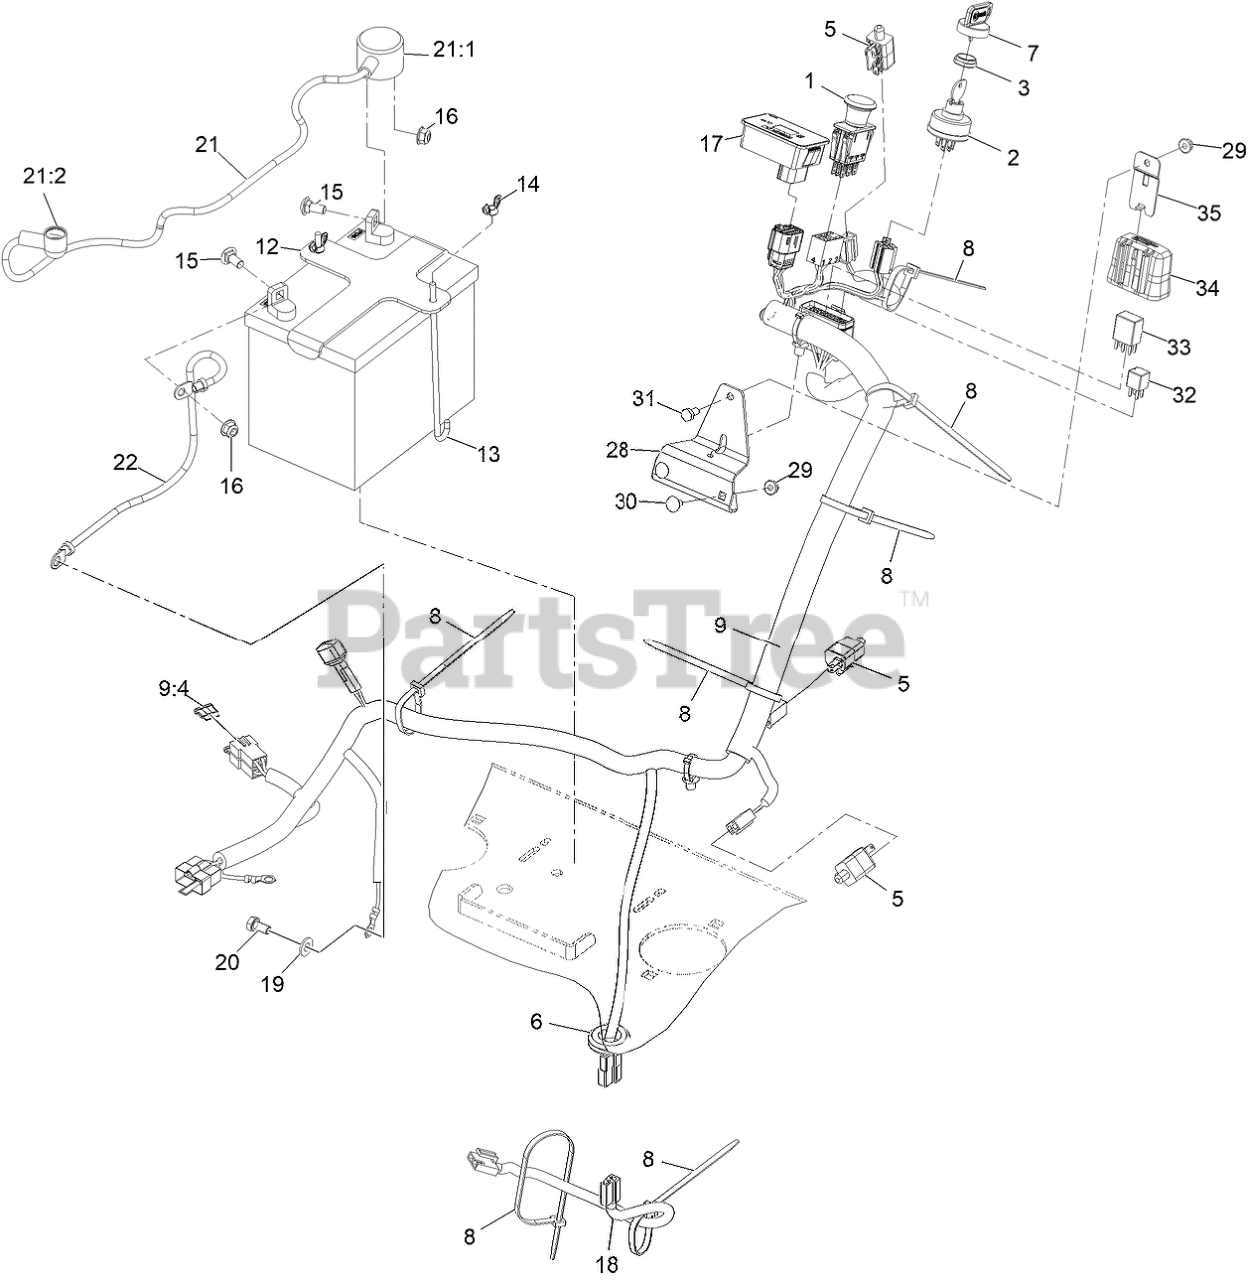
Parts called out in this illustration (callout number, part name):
1	SWITCH-PTO
2	SWITCH, KEY START
3	NUT-SWITCH, IGNITION
6	GROMMET
7	KEY-IGNITION
8	TIE-CABLE
9	HARNESS-WIRING
9:4	FUSE-BLADE TYPE, 20 AMP
12	BRACKET, BATTERY HOLD DOWN
13	BOLT-HOLDDOWN
14	WINGNUT
15	BOLT-CARR
16	NUT-HF, NI
17	MODULE-HOUR METER
18	HARNESS-CLUTCH PIGTAIL
19	WASHER-PLAIN
20	SCREW-HH
21	POSITIVE BATTERY CABLE AS
21:1	INSULATOR-SOLENOID
21:2	INSULATOR-BATTERY
28	BRACKET, MOUNTING PDM
30	SCREW-CARR
31	SCREW-HH
32	RELAY-MICRO
33	RELAY-MICRO 280, SPDT
34	COVER-BLOCK, FUSE
35	CLIP-MOUNTING
